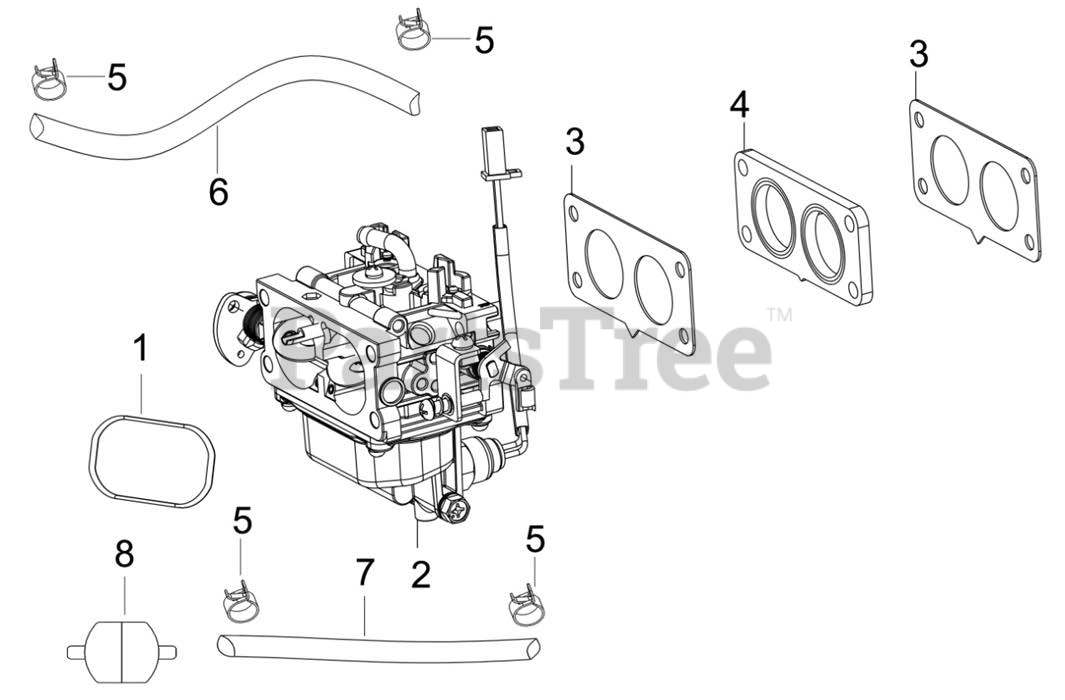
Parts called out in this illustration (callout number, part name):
1	SEAL RING
2	CARBURETOR
3	CARBURETOR GASKET
4	HEAT INSLTNG PAD FOR CARBURTOR
5	LOOP, TUBE
6	OIL TUBE
7	OIL TUBE
8	FILTER, FUEL
